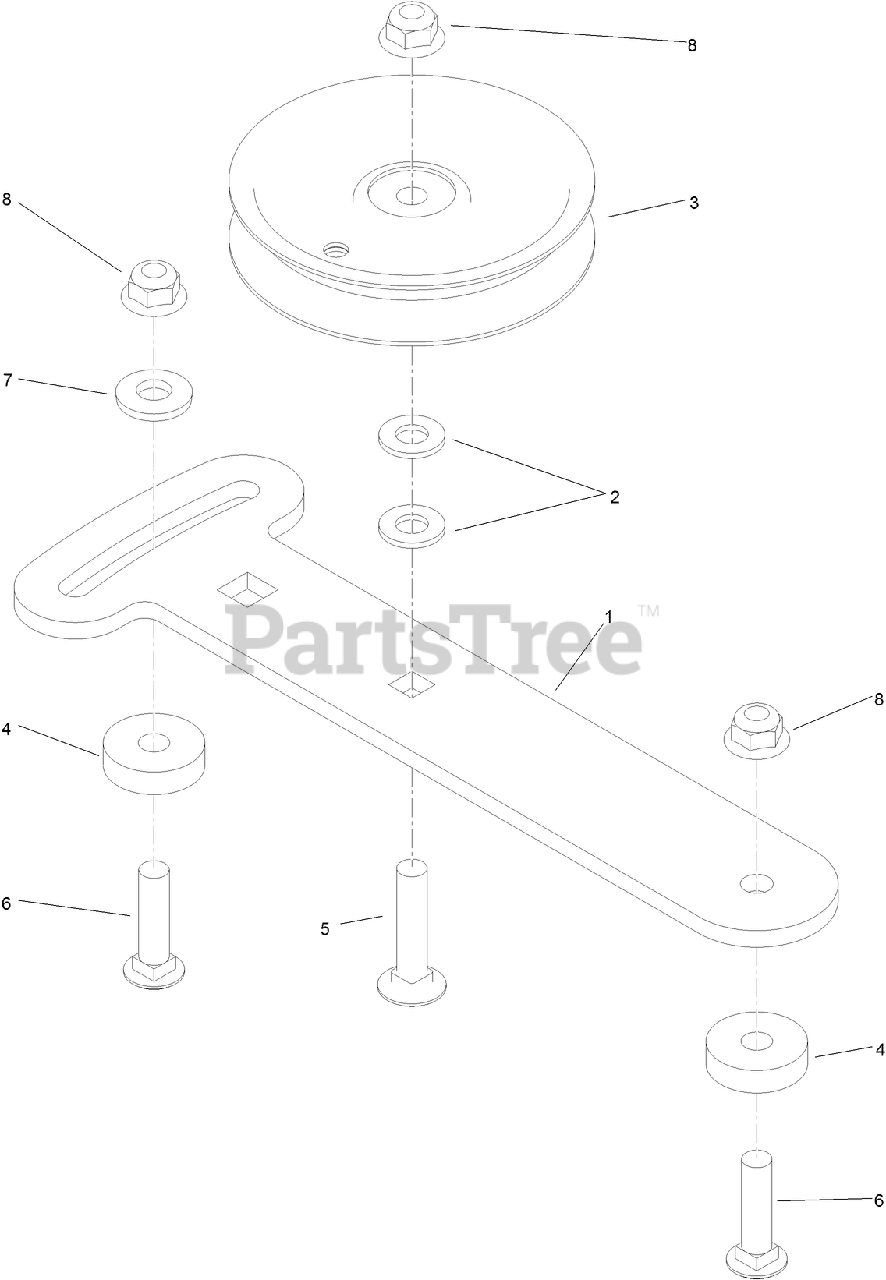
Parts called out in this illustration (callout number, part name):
1	PLATE-IDLER
2	WASHER-FLAT
3	PULLEY-IDLER
4	Spacer
5	SCREW-CARR
6	SCREW-CARR
7	WASHER-BELLEVILLE
8	NUT-HF, NI
